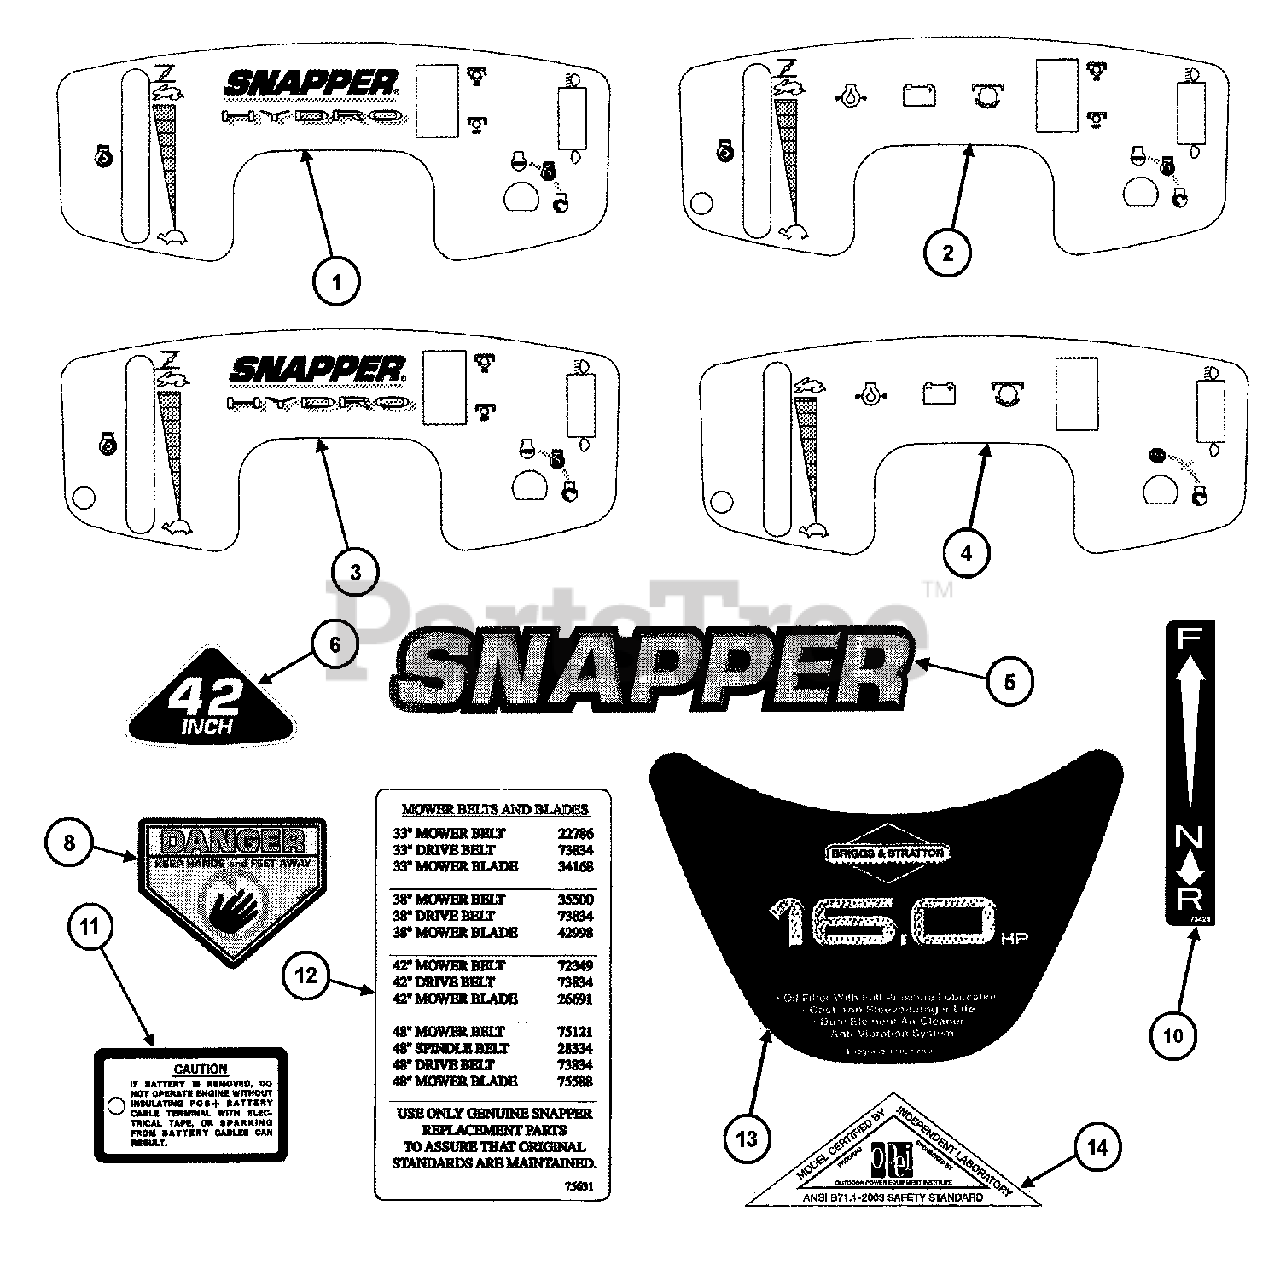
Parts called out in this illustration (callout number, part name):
1	DECAL, Console- w/Headlights
2	DECAL, Console- w/Indicator Lights
3	DECAL, Console- Headlight/Choke- LT1642
4	DECAL, Console Indicators
5	DECAL, Snapper- Hood- 3D, Silver Letters
6	DECAL - 42 Inch
8	DECAL, Danger, Cut Finger
10	DECAL, Shift Cover Hydro
11	TAG, Caution
12	DECAL, Service Parts, Tractor Domestic
13	DECAL, Engine, 16HP OHV B&S
14	DECAL, OPEI, Walk/Ride
